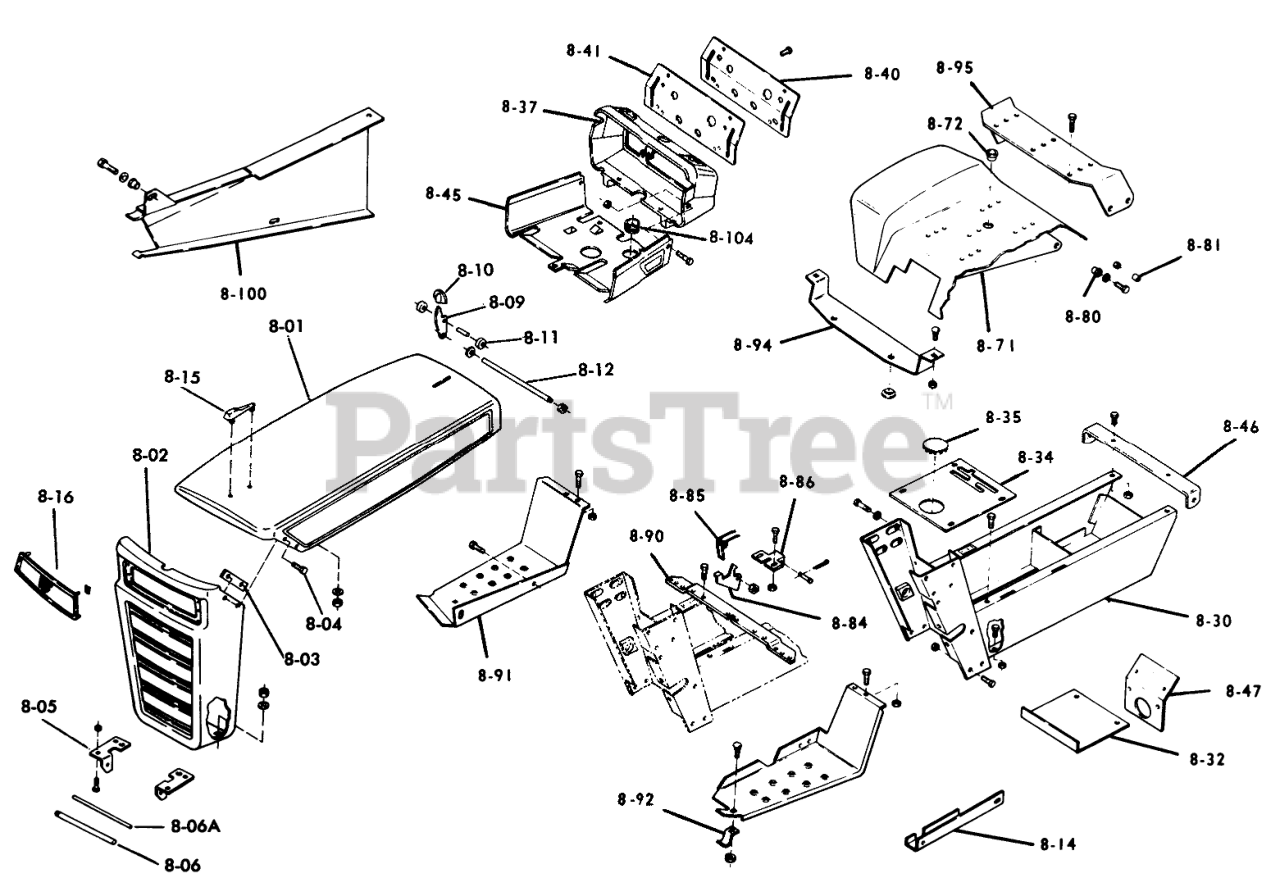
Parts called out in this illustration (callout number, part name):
8-01	Hood
8-02	Spacer Sleeve
8-03	Plate, Grille
8-04	Bolt
8-05	GRILL PIVOT BRKT
8-06	GRILL PIVOT ROD
8-06A	ROD-HOOD STOP
8-07	GROMMET
8-09	LEVER HOOD LATCH
8-10	KNOB
8-11	Roller
8-12	Rod Latch
8-15	Hood Ornament
8-30	Hoodstand Assembly
8-32	Cover-Dust
8-34	Cover Plate
8-35	Plug Button
8-37	Housing
8-40	Dash Panel
8-41	BACK UP PLATE
8-44	Tape
8-45	Support-Tank
8-46	Bracket
8-47	Instrument Backet
8-71	FENDER R
8-80	BUSHING-FLANGED
8-81	SPACER
8-84	Fender Latch
8-85	Spring
8-86	BRACKET FENDER LATCH
8-90	Bracket-Footrest
8-91	Footrest-RH
8-92	BRACKET
8-94	Fender Bracket
8-95	Bracket Fender Hinge
8-100	Machine Bushing
8-101	Front Belt Guide
8-102	Footrest Pad-L.H.
8-103	Channel
8-104	Grommet
